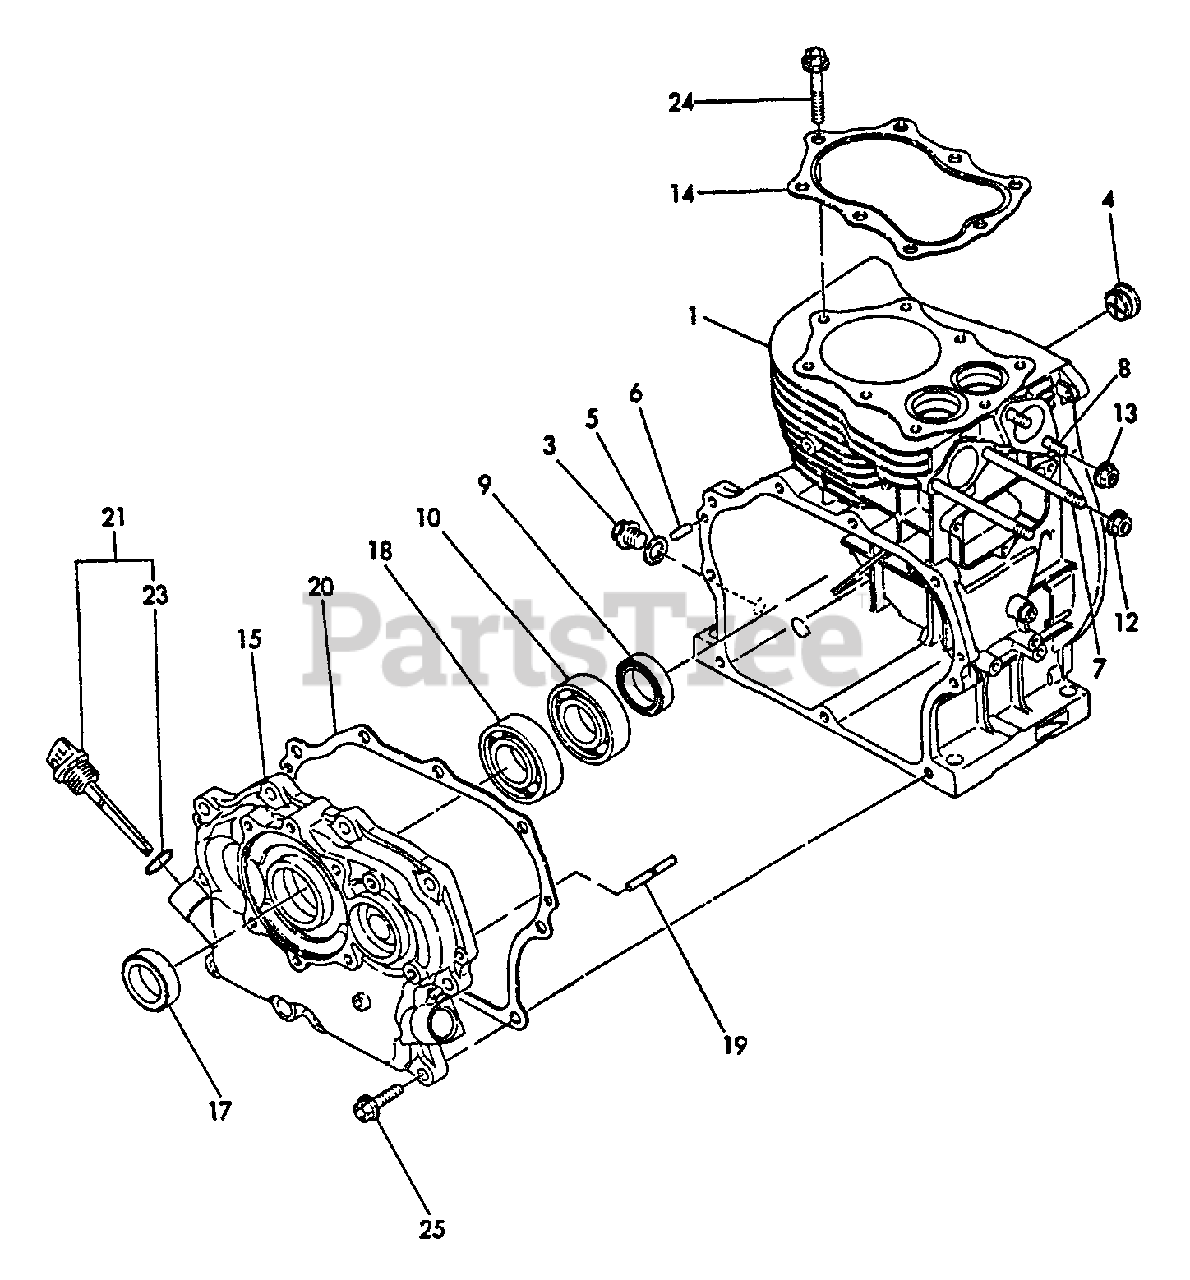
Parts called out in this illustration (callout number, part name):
1	CYLINDER BLOCK SET
3	PLUG, DRAIN
4	PLUG
5	GASKET
6	PARALLEL PIN 6×16
7	STUD M8×95 PLATED
8	STUD -- PLATED
9	SEAL, OIL
10	BEARING, BALL 6206C4
12	U-NUT M8
13	U-NUT M8
14	GASKET, CYLINDER
15	COVER, CRANKCASE
17	SEAL, OIL
18	BEARING, BALL 6206C4
19	SHAFT, GOVERNOR
20	GASKET, CRANKCASE
21	CAP ASSY
23	O-RING 1A P-18.0
24	BOLT - 8×50
25	BOLT - 8×30 -- PLATED
